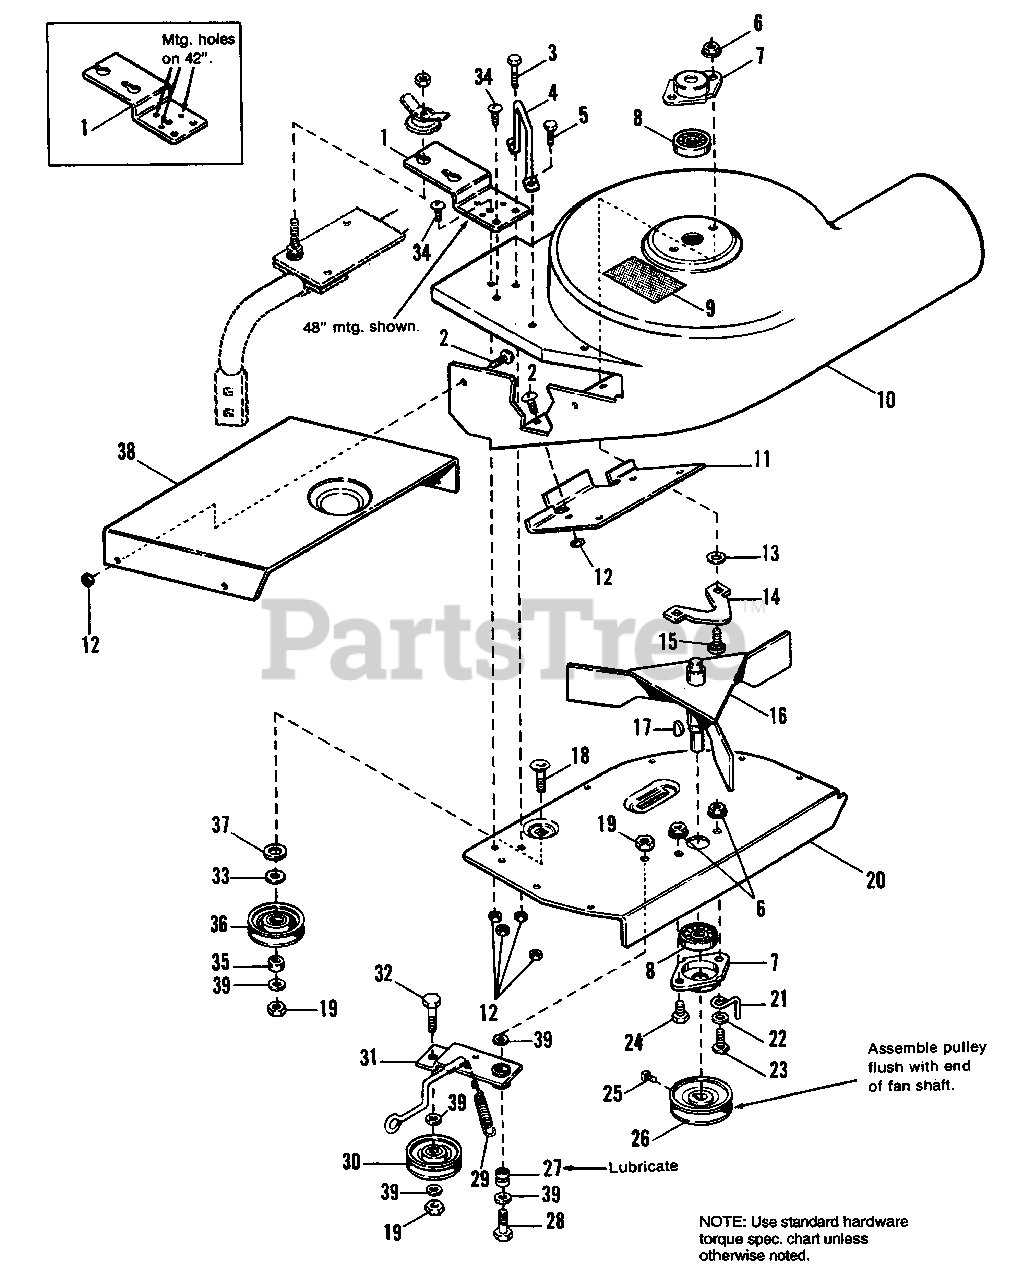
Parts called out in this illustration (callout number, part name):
1	MOUNTING PLATE
2	CAPSCREW, Hex Hd., 1/4-20 x 5/8
3	CAPSCREW, Hex, 1/4-20 x 7/8
4	STOP, Deflector
5	CAPSCREW, Hex, 1/4-20 x 3/4
6	NUT, Range, Lock, 5/16-18
7	BEARING, Retainer
9	DECAL, Warning
10	HOUSING, Blower
11	HOOK, Stoneguard
12	NUT, Hex Flange Whizlock, 1/4-20
13	PUSH NUT, 5/16
14	PLATE, Flange
15	CARRIAGE BOLT, 5/16-18 x 3/4
16	FAN ASSY.
17	KEY, Woodruff
18	CARRIAGE BOLT, 3/8-16 x 1-1/4
19	NUT, Hex Jam Lock, 3/8-16
20	PLATE, Shroud
21	STOP, Belt
22	WASHER, Plain, 11/32
23	CAPSCREW, Thin Hd., 5/16-18 x 3/4
24	CAPSCREW, Hex Hd., 5/16-18 x 1/2
25	SETSCREW, Socket Hd., 5/16-18 x 5/16
26	PULLEY, Driven
27	SPACER
28	CAPSCREW, Hex Hd., 3/8-16 x 1-1/2
29	SPRING, Tension
30	PULLEY, Idler, Adjustable
31	IDLER ARM ASSY.
32	CAPSCREW, 3/8-16 x 1
33	LOCKNUT, Hex, Jam, 3/8-16
34	SCREW, Truss Hd., 1/4-20 x 3/4
36	PULLEY, Idler, Fixed
37	WASHER, Plain, 1/2
38	COVER, Top
39	WASHER, 13/32
